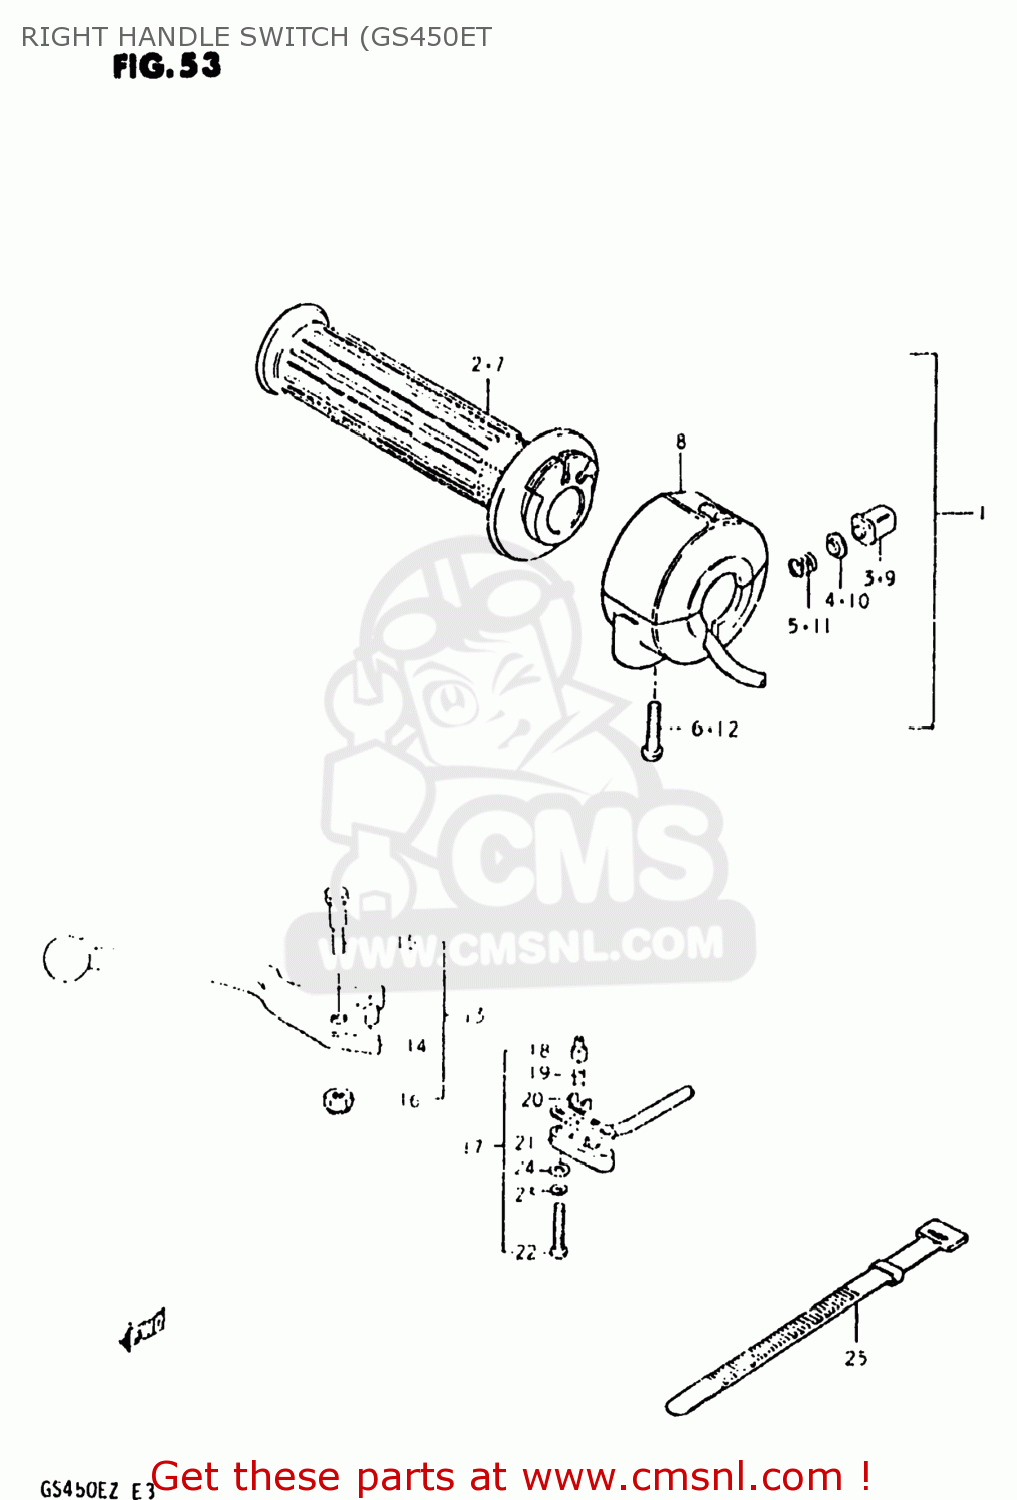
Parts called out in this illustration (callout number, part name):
1	CASE ASSEMBLY,THROTTLE
2	GRIP,THROTTLE
3	BUTTON,HORN
4	CONTACT
5	SPRING
6	SCREW
7	GRIP,THROTTLE
8	CASE ASSEMBLY,THROTTLE
9	BUTTON,HORN
10	CONTACT
11	SPRING
12	SCREW
13	LEVER ASSEMBLY,BRAKE
14	LEVER,BRAKE
15	BOLT
16	NUT 6MM
17	SWITCH ASSEMBLY
18	HOLDER
19	SPRING
20	PLATE
21	COVER,FR BK TERMINAL BASE
22	SCREW
23	LOCK WASHER
24	WASHER
25	CLAMP(L:120)
